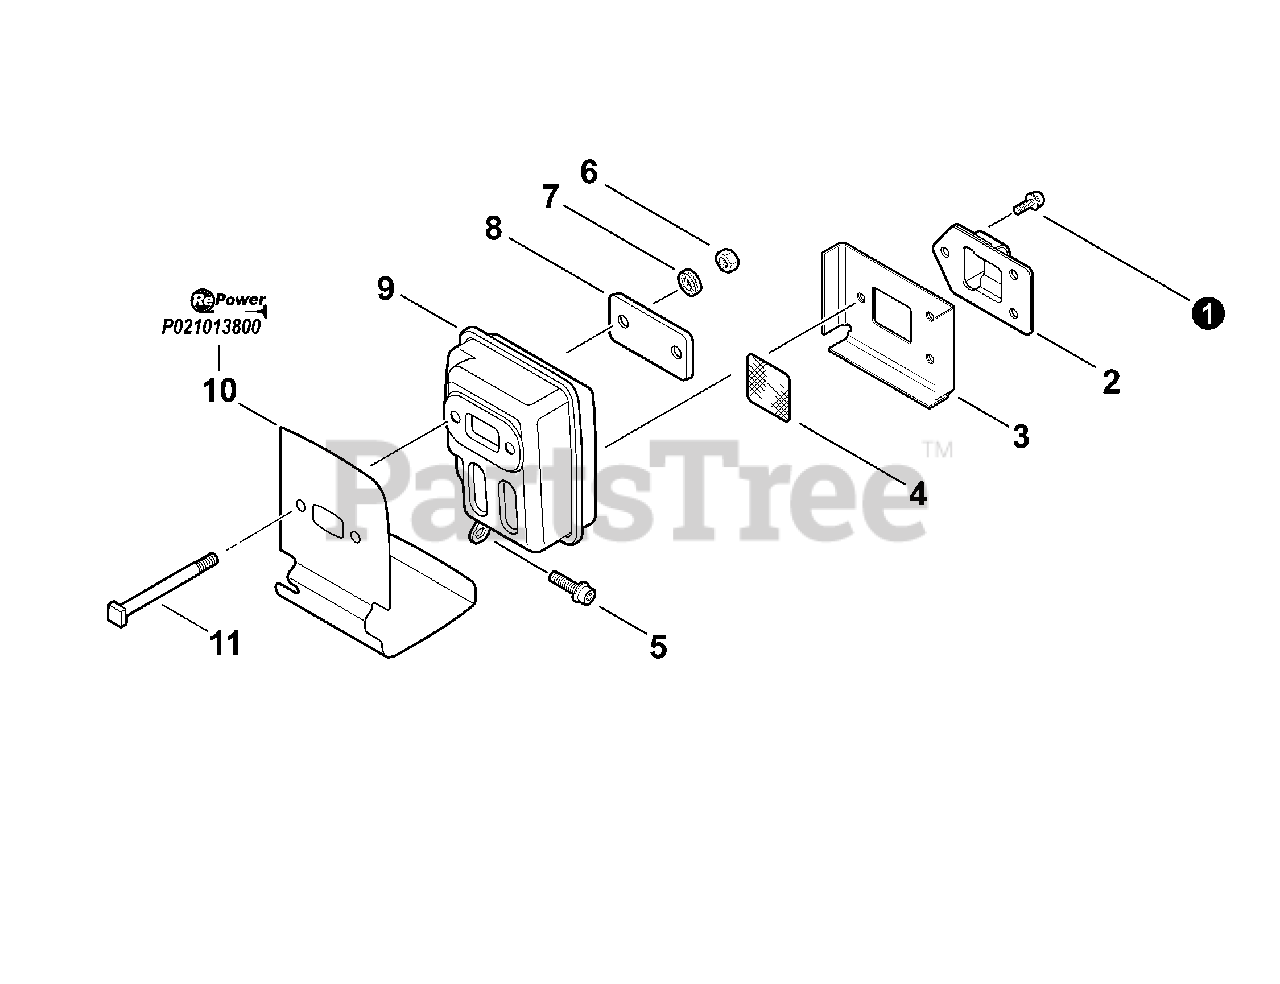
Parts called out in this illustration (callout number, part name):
1	SCREW 4×10
2	GUIDE, EXHAUST
3	GASKET, EXHAUST
4	SCREEN, SPARK ARRESTER
5	BOLT 5×16
6	NUT M5
8	PLATE, EYE
9	MUFFLER
10	HEAT SHIELD, EXHAUST
11	BOLT 5×60
